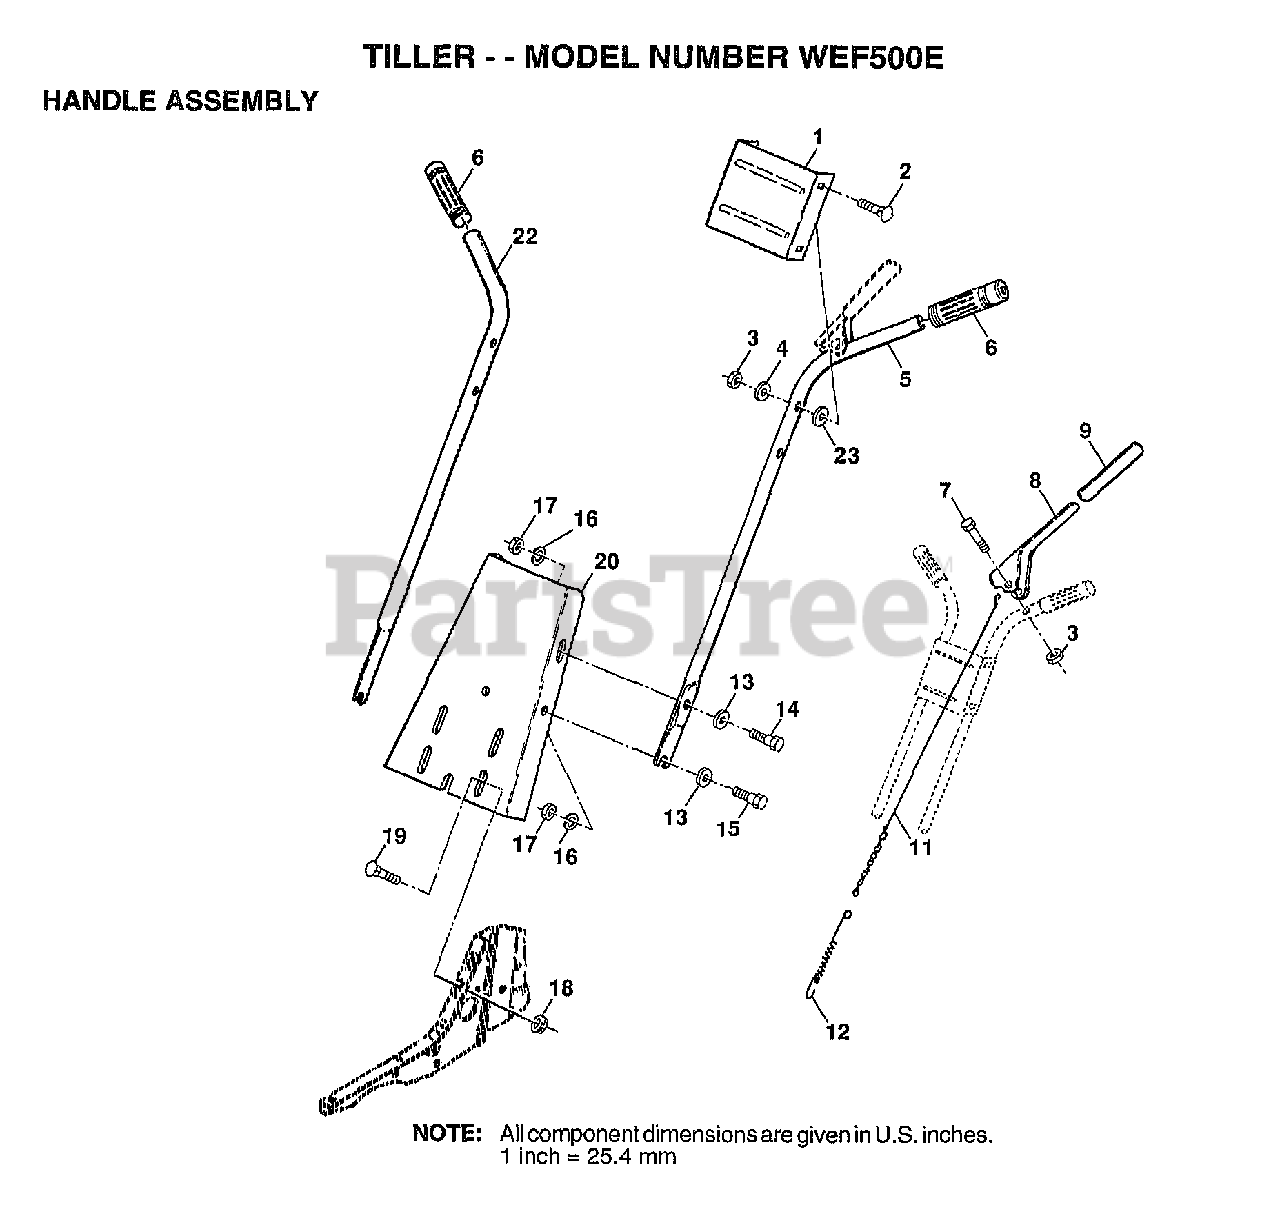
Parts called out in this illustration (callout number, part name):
1	PANEL.CNTRL.HDLE.
2	BOLT
4	WASHER
5	HANDLE LH
7	BOLT.HEX.5/16-1.5
9	GRIP T
12	SPRING EXT TI
13	WASHER
15	BOLT
16	LOCKWASHER
17	NUT.HEX.5/16-18
18	NUT
19	BOLT
20	PANEL.HANDLE.TILL
22	HANDLE RH
23	WASHER
